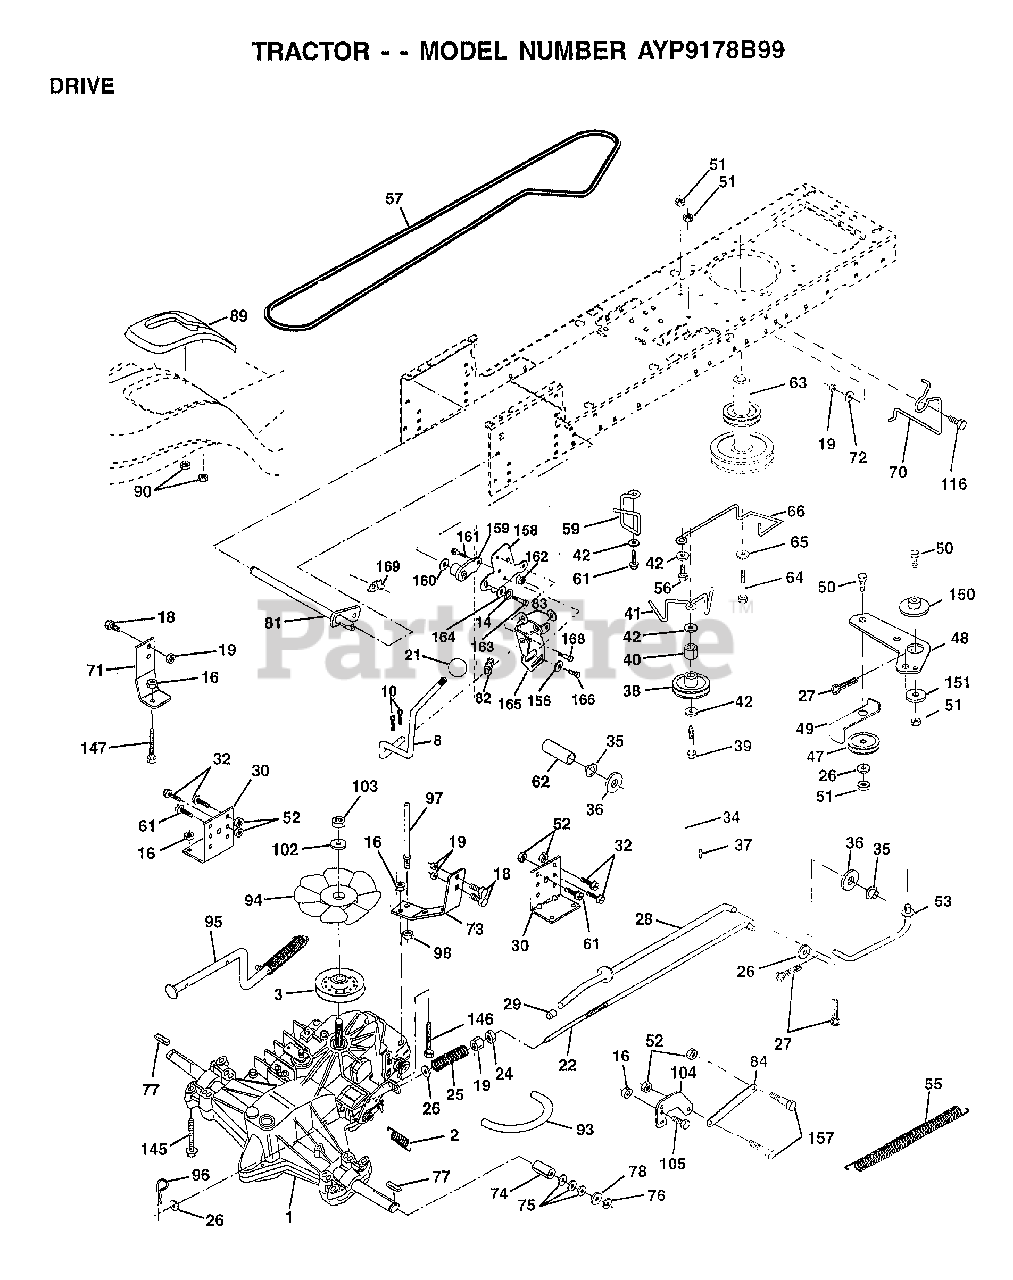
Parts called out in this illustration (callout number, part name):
2	SPRING RET BRAKE
3	PULLEY.TRANSAXLE
8	RODL.SHIFT.FEND.ADJ.STLT
10	PIN COTTER 1/8
14	LOCKWASHER
16	NUT
18	BOLT
19	NUT
21	KNOB T (1/2-HOLE)
22	ROD.BRAKE.HYDRO.
24	NUT
25	SPRING ROD LT
26	WASHER
27	COTTER PIN
28	ROD.BRAKE.PARK.LT
30	TRANSAXLE MTG BKT
32	BOLT
34	SHAFT ASM-PEDAL F
35	NYLON BEARING
36	WASHER LT
38	FLAT IDLER PULLEY
39	BOLT
40	SPACER T
41	"KEEPER,BELT.IDLER FLAT"
42	WASHER
48	BELLCRANK.CLUTCH
49	RETAIN BELT
53	"LINK, CLUTCH T"
55	"SPRING, RETURN LT"
57	"BELT.GD DRV 82"""
59	KEEPER BELT CNTSP
61	SCREW
62	PEDAL COVER T
63	PULLEY.ENGINE
64	BOLT
65	LOCKWASHER
66	KEEPER-BELT
70	KEEPER BELT ENG
71	STRAP TORQ LH HYD
72	WASHER
73	"STRAP-TORQUE,RH"
74	SPACER SPLIT
75	WASHER
76	E-RING LT
77	SQUARE KEY
78	WASHER
81	SHAFT.ASM.CROSS
82	SPRING.SHIFT.STLT.GREY
83	WASHER
84	LINK.TRANSAXLE.LT/YT
89	CONSOLE.SHIFT
90	NUT
93	"LINE FUEL HYD 4"""
94	"FAN 7"" HYDRO"
95	CONTROL.ASM.BYPASS.HYDRO.99
96	RETAINER M
97	BOLT KEEPER RH
98	NUT
102	WASHER BELLEVILLE
104	ARM CONTROL HYDRO
105	SCREW CAP 5/16-18
116	BOLT RDHD 3/8-16
145	BOLT.HEX.FLGHD
146	BOLT.HEX.FLGHD.
147	BOLT.HEX.FLGHD
150	BUSHING.BELLCRANK.GRD.DR
151	WASHER
156	WASHER.SRRTD.5/16
157	"BOLT,SHOULDER"
158	BRKT.SHIFT.MOUNT
159	HUB.SHIFT
160	WASHER
161	BOLT T
164	WASHER.5/8X.281X10GA
165	BRKT.PIVOT.LEVER
166	SCREW.5/16-18X5/8
168	BOLT.SHOULDER.5/16-18X.561
169	PLATE.FASTENING
